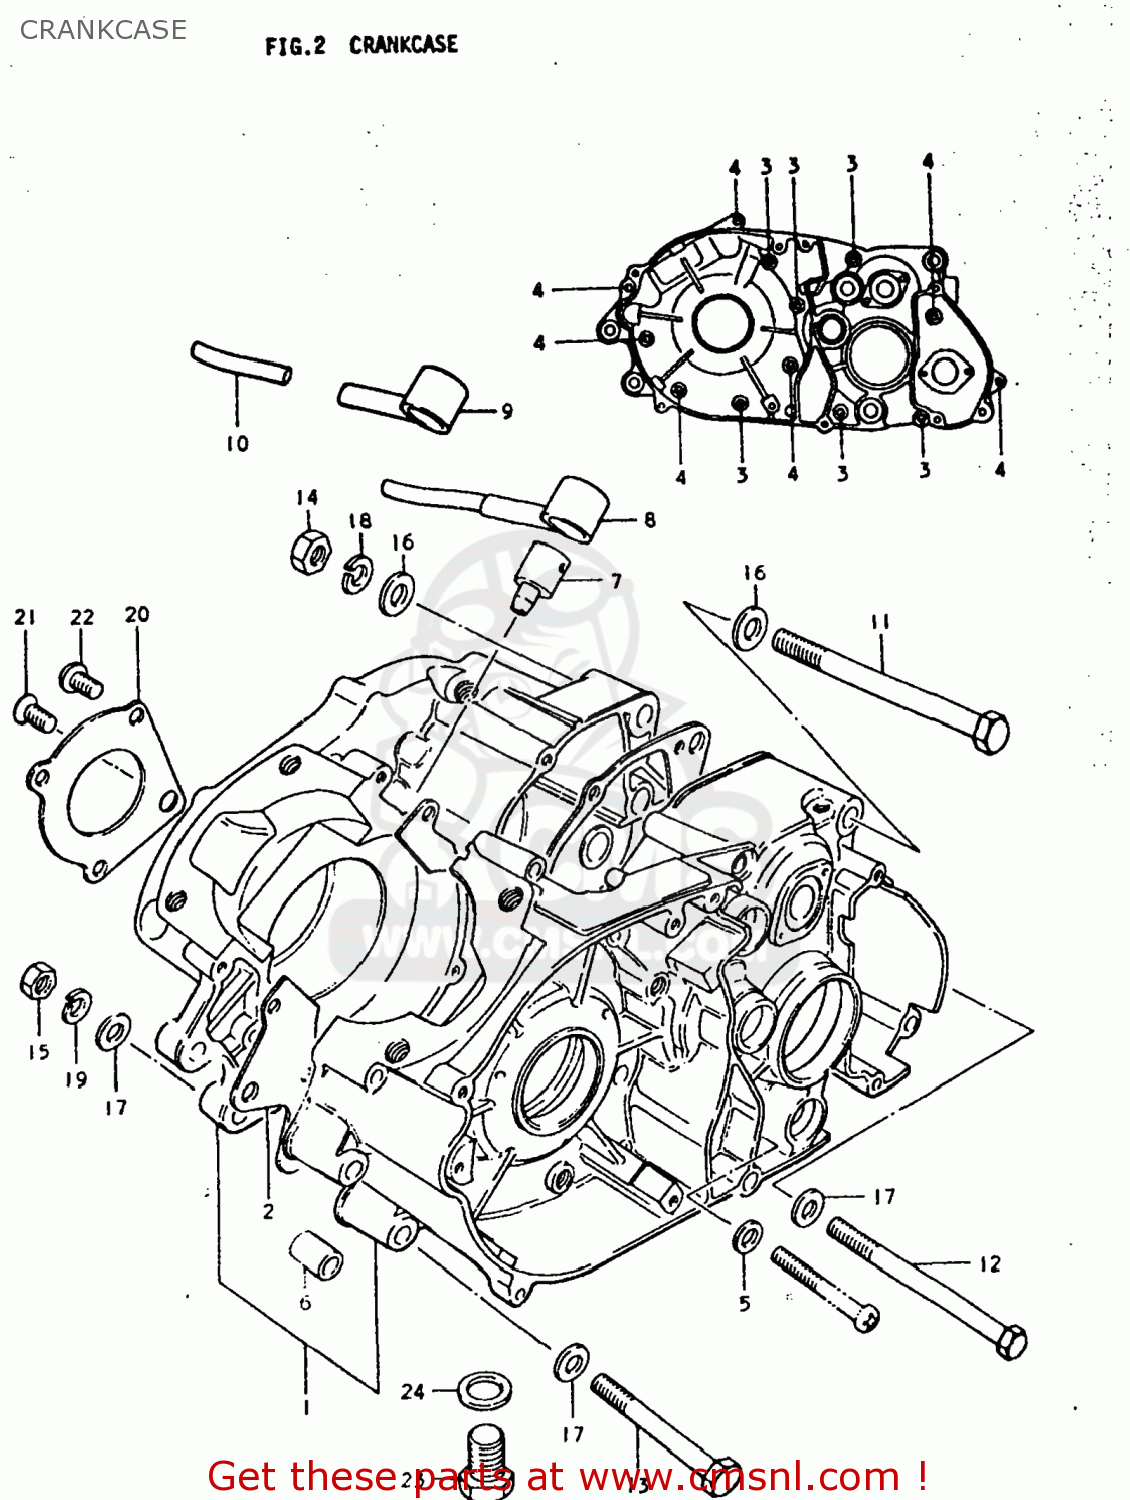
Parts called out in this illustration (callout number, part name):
1	CRANKCASE SET
2	GASKET,CRANKCASE (MCA)
3	SCREW
4	SCREW (6X45)
5	WASHER 6MM
6	PIN
7	PLUG,TRANSMISSION BREATHER
8	PLUG,BREATHER
9	GASKET (NAS)
10	HOSE
11	BOLT 10X120
12	BOLT 8X120
13	BOLT
14	NUT
15	NUT
16	WASHER
17	WASHER
18	LOCK WASHER
19	LOCK WASHER
20	PLATE,OIL RESERVOIR
21	SCREW
22	SCREW 6X12
23	PLUG
24	GASKET(14X19.2X2) (NAS)
